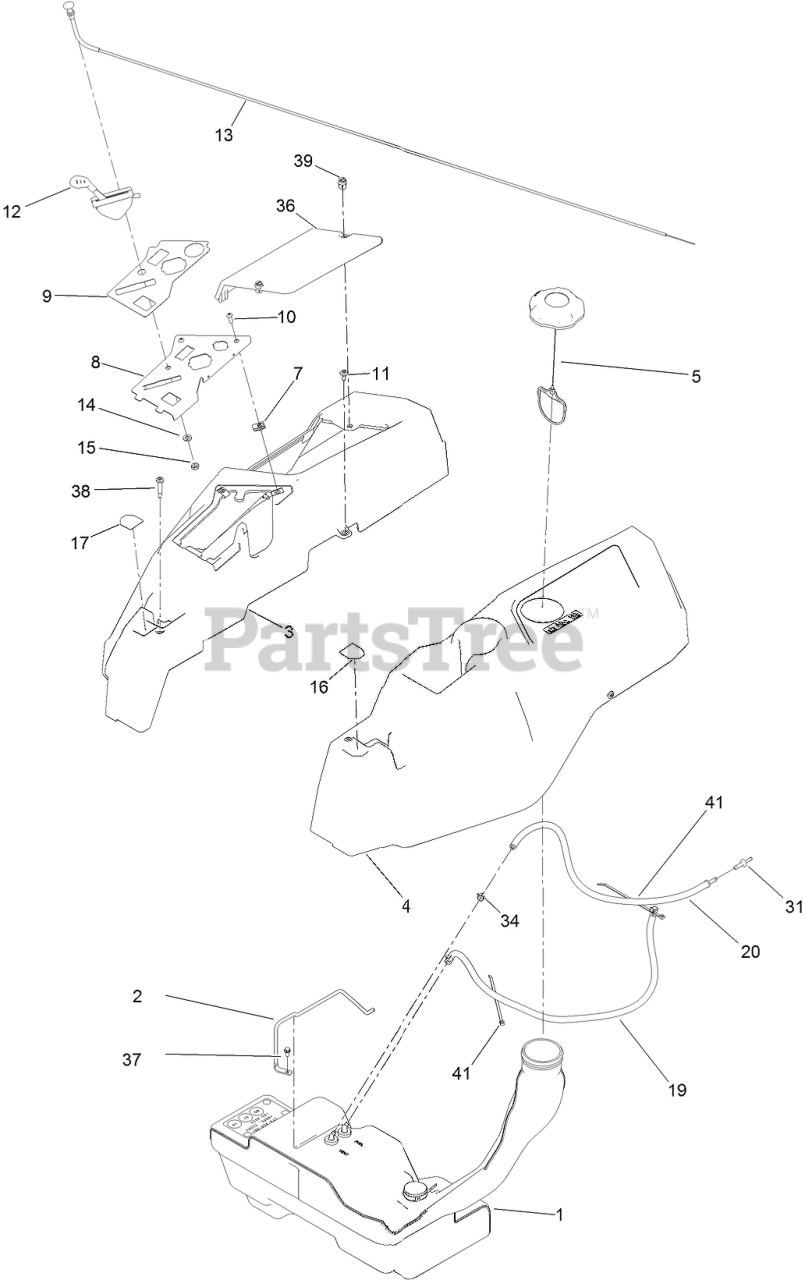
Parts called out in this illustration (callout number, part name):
1	FUEL TANK ASM
2	ROD-HOLD DOWN
3	POD-RH
4	POD-LH
5	CAP-FUEL, RATCHETING
8	PANEL-CONTROL
9	DECAL-CONTROL W/CHOKE
10	SCREW-PRH
11	SCREW-SHOULDER
12	CABLE-THROTTLE
13	CABLE-CHOKE
14	WASHER-LOCK
15	NUT-HJ
16	DECAL-LEVER, CONTROL (LH)
17	DECAL-LEVER, CONTROL (RH)
19	HOSE-FUEL
20	HOSE-FUEL
31	ADAPTOR-ORIFICE
34	CLAMP-HOSE
36	COVER-BATTERY
37	SCREW-HWH
38	SCREW-SHOULDER
39	FASTENER
41	TIE-CABLE
